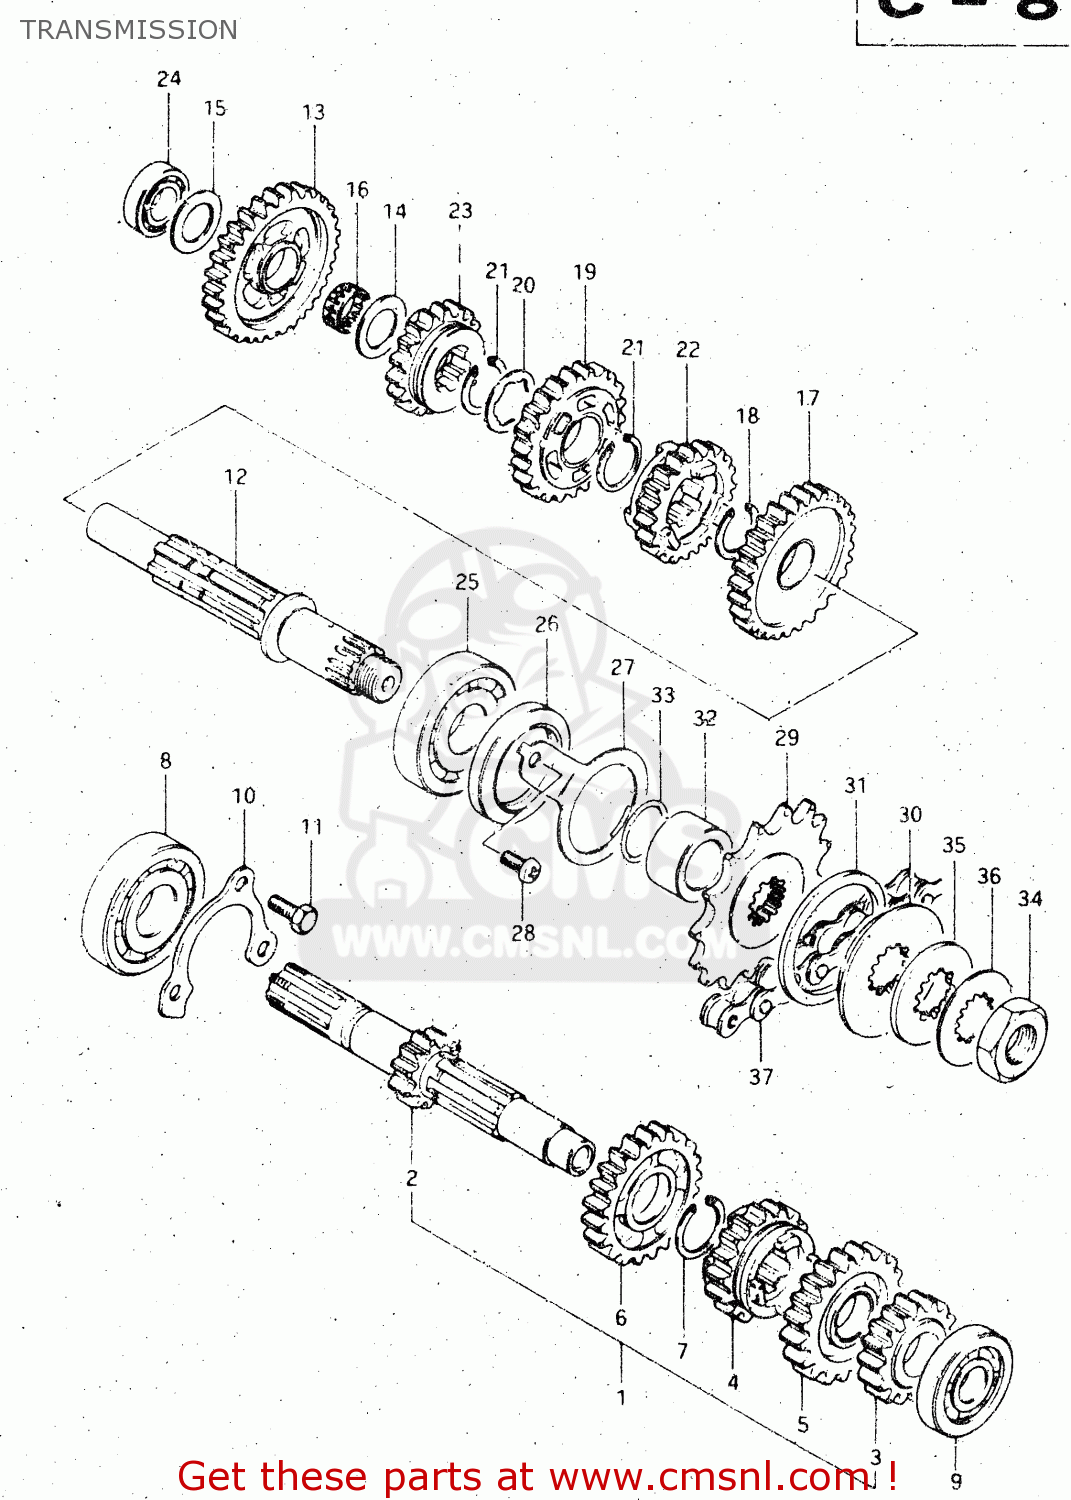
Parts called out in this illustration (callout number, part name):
1	SHAFT,COUNTER
2	SHAFT,COUNTER
3	GEAR,SECOND DRIVE
4	GEAR,THIRD DRIVE
5	GEAR,FOURTH DRIVE
6	GEAR,FIFTH DRIVE
7	CIRCLIP
8	BEARING
9	BEARING
10	PLATE,COUNTERSHAFT BEARING
11	BOLT, 8X1.25X1
12	SHAFT,DRIVE
13	GEAR,FIRST DRIVEN
14	WASHER
15	WASHER
16	BEARING(20X24X10).8
17	GEAR,SECOND DRIVEN
18	CIRCLIP
19	GEAR,THIRD DRIVEN
20	WASHER,LOCK
21	CIRCLIP
22	GEAR,FOURTH DRIVEN
23	GEAR,FIFTH DRIVEN
24	BEARING(20X42X12)
25	BEARING
26	SEAL,OIL(32X42X7)
27	PLATE,DRIVESHAFT OIL
28	BOLT
29	SPROCKET,ENGINE(NT:15)
30	HOLDER, DAMPER
31	DAMPER,ENGINE SPROCKET
32	SPACER (22X32X13.4)
33	O RING(D:1.7,ID:22)
34	NUT
35	SPACER,ENGINE SPROCKET
36	WASHER,LOCK
37	CHAIN ASSEMBLY,DRIVE
